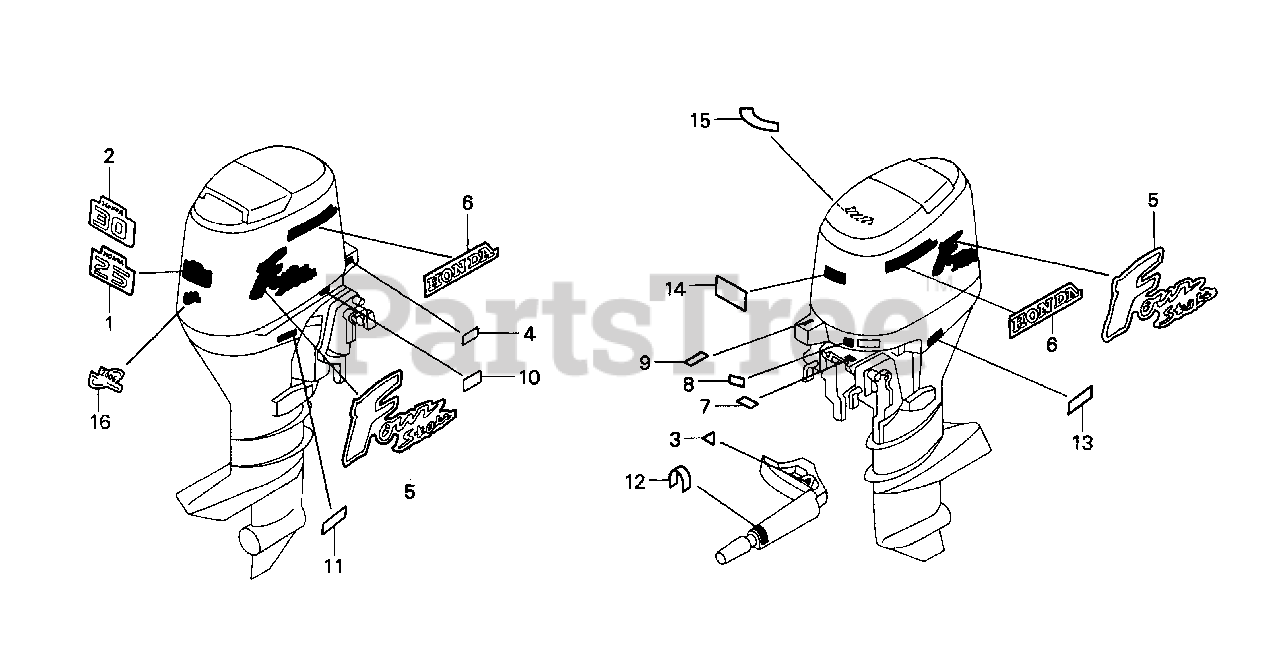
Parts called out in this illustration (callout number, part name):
1	MARK, RR. EMBLEM
3	MARK, EMERGENCY SWITCH INDICATION (ENGLISH)
5	MARK, SIDE
6	MARK, SIDE STRIPE
7	LABEL, SPECIFICATION
8	MARK, OIL PRESSURE
9	MARK, CHANGE (ENGLISH)
11	LABEL, OIL CAUTION (ENGLISH)
12	MARK, THROTTLE (ENGLISH)
13	LABEL, STORING CAUTION (ENGLISH)
14	LABEL, OPERATOR CAUTION (E)
14	LABEL, CAUTION OPERATOR (ENGLISH)
15	MARK, EMERGENCY START (ENGLISH)
